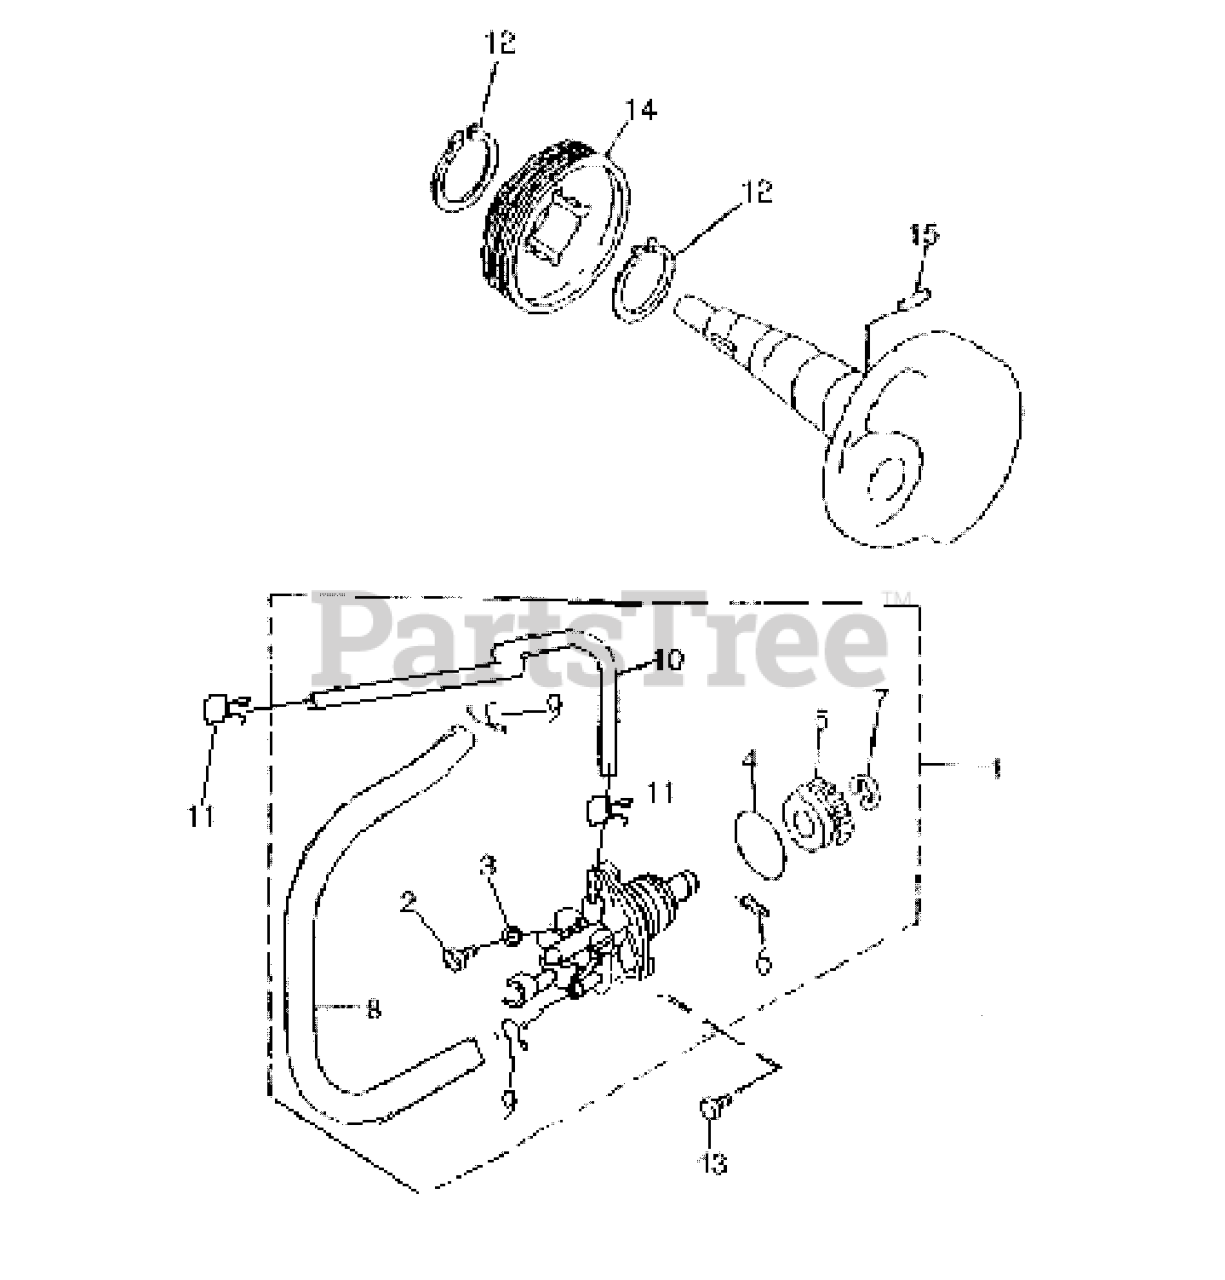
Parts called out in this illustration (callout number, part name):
1	OIL PUMP ASSY
2	SCREW
3	WASHER
4	O-RING
5	GEAR
6	PIN
7	CIRCLIP
8	HOSE
9	HOSE CLIP
10	HOSE
11	HOSE CLIP
12	CIRCLIP
14	PUMP DRIVE GEAR
